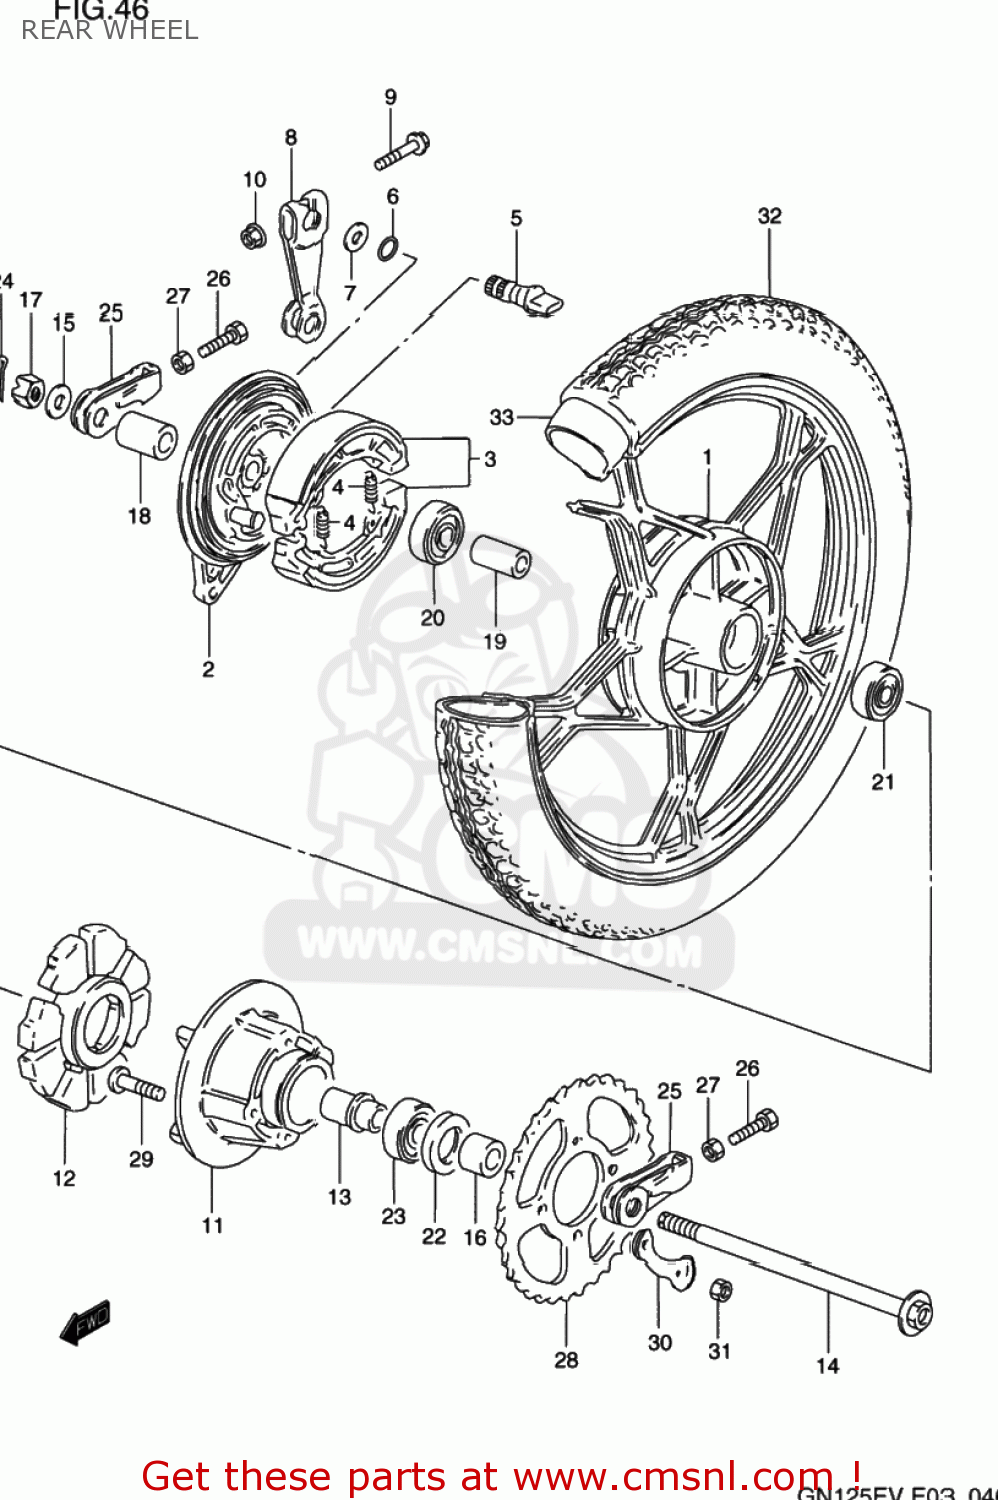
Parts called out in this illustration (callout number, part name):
1	WHEEL,RR(2.15X10)
2	PANEL,RR BRAKE ANCHOR
3	SHOE SET,BRAKE (NAS)
4	SPRING(L:34)
5	CAM,BRAKE
6	O RING(D:2.5,ID:13.8)
7	WASHER(14.5X22X1.6)
8	LEVER,RR BRAKE CAM
9	BOLT
10	NUT
11	DRUM,RR SPROCKET MOUNTING
12	ABSORBER,RR HUB SHOCK
13	RETAINER,RR SPROCKET DRUM
14	AXLE,RR
15	WASHER
16	SPACER(15X28X19)
17	NUT
18	SPACER(15.2X26X33)
19	SPACER(15.3X21.7X63)
20	BEARING
21	BEARING
22	SEAL,OIL(28X47X7)
23	BEARING(20X47X14)
24	COTTER PIN
25	ADJUSTER,CHAIN
26	BOLT(8X50)
27	NUT
28	SPROCKET,RR(NT:42)
29	BOLT
30	WASHER
31	NUT
32	TIRE,RR(3.50-16 4PR)
33	TUBE
